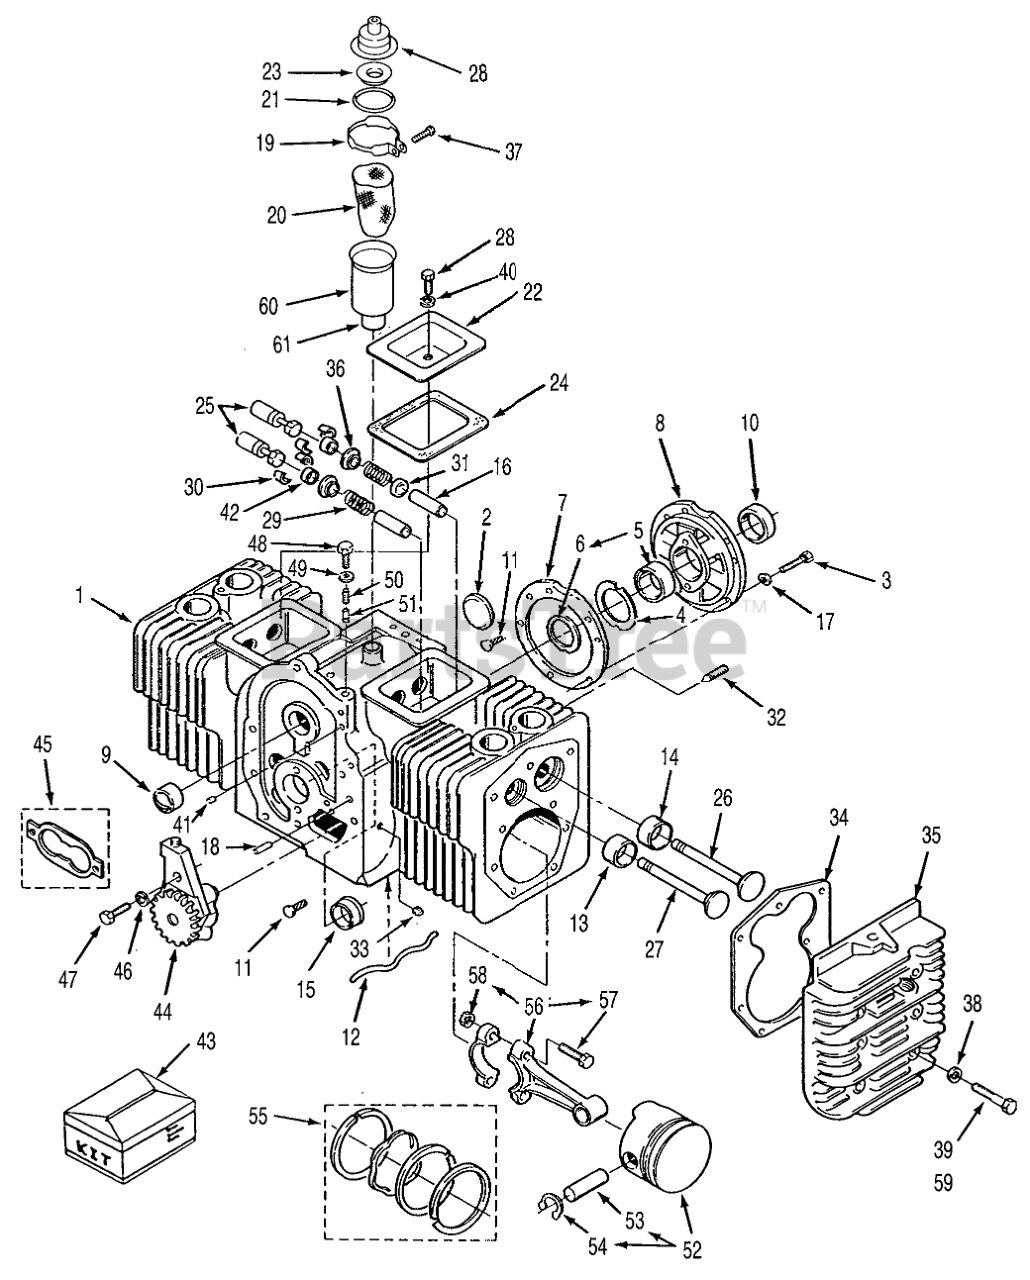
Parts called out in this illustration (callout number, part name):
1	SHORT-BLOCK
2	Plug
3	Bolt 3/8-16x 1-1/4
4	Shim 0.005"
5	Rear Crankshaft Bearing-STD
6	ThrustWasher
7	Gasket
8	Bearing Plate
9	Camshaft Brg
10	Oil Seal
11	Screw
12	Oil Tube
13	Standard
14	Standard
15	Standard
16	Exhaust Valve Guide
17	Lockwasher 3/8
18	Pin
19	Clamp
20	Baffle
21	Seal
22	VALVE-COVER L.H.
23	Screen
24	Gasket
25	Tappet
26	Intake Valve
27	Exhaust Valve
28	HHCS 1/4-20 X 1 3/4
29	Spring
30	VALVE SPRING LOCK
31	Seal
32	Screw
33	Plug
34	Gasket
35	Right Side
36	Washer
37	Screw #8 x 3/4
38	Washer
39	Bolt
40	Washer
41	Plug
42	Cap-Valve
43	Engine Gasket Kit
44	Oil Pump
45	Oil Pump Gasket Kit
46	Washer-Lock
47	Bolt
48	Bolt
49	Washer
50	Spring
51	Piunger
52	Piston Pin & Retaining Rings-STD
53	Pin-Piston
54	Retaining Ring
55	Standard
56	CONNECTING ROD W/NUT
57	Rod Bolt
58	Nut
59	Special Bolt 2.375" Long
60	Breather Cap & Valve
61	Breather Tube
